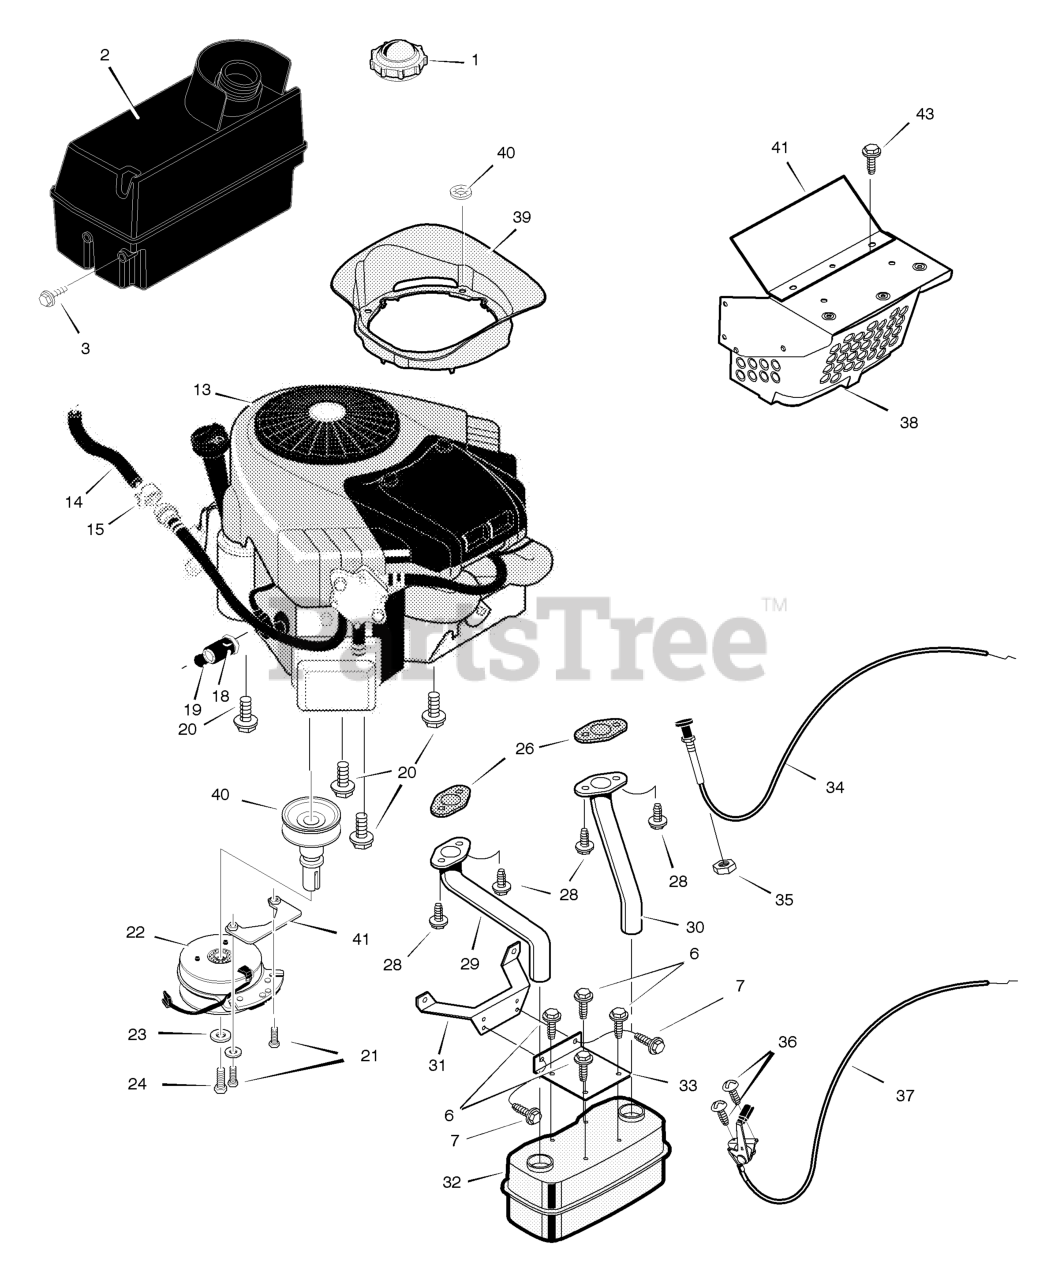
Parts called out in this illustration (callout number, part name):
1	Cap, Fuel
2	Tank, Fuel
13	Engine, Briggs & Stratton *
14	Fuel Line (Must cut to length)
15	Clamp
18	Valve, Oil Drain
19	Cap, Oil Drain
20	Bolt
22	Clutch, Electric
23	Washer
29	Tube, Right Exhaust
30	Tube, Left Exhaust
31	Bracket, Muffler Mount
32	Muffler
33	Bracket, Muffler
35	Nut
37	Control, Throttle
38	Shield Assembly, Heat
40	Retainer, Push
41	Shield, Upper Heat
